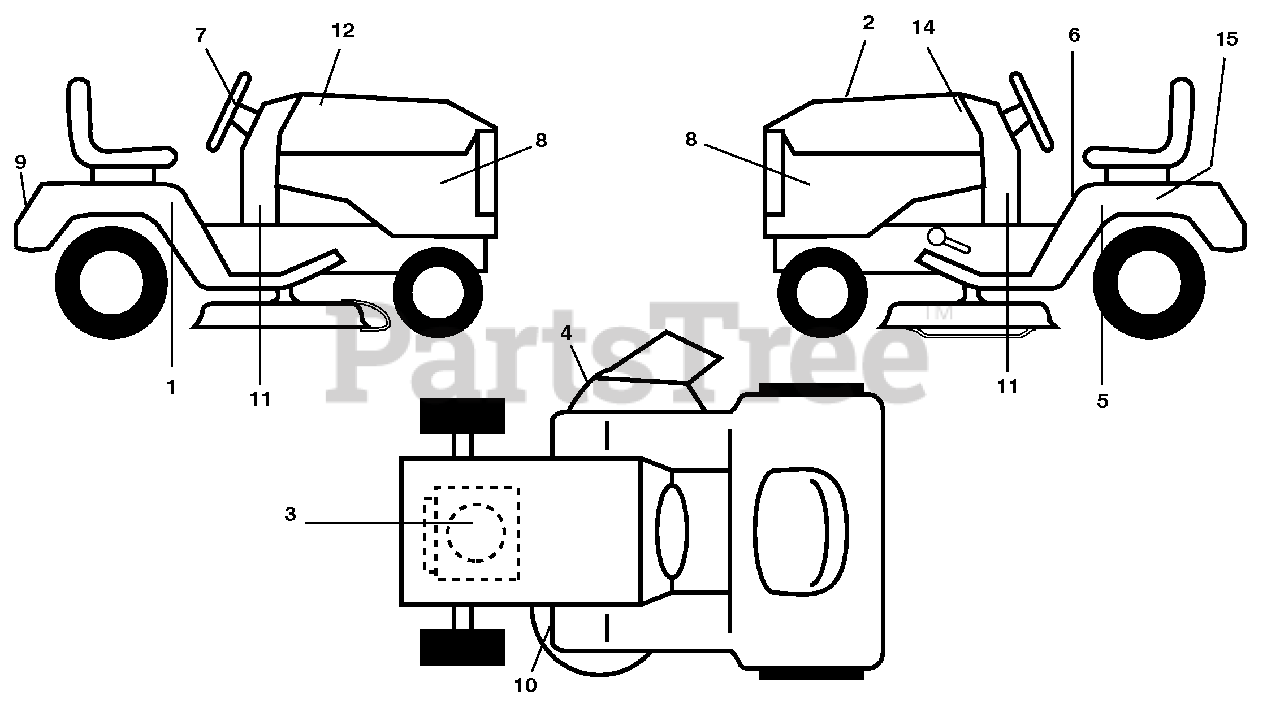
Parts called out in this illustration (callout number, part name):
1	Decal, Fender RH
2	Decal, Replacement
3	Decal, Engine HP
4	Decal, Warning
5	Decal, Fender LH
6	Decal, Fender Danger Eng/Fr
7	Decal, Ins Str Wh
8	Decal, Side Panel
9	Decal, Fender
10	Decal, V-Belt Sch.
11	Decal, Lower Dash
12	Decal, Hood RH
14	Decal, Hood LH
15	Decal, Caution, Battery
15	Decal, Handle Lft Height Adj.
15	Pad Footrest LH
15	Pad Footrest RH
15	Manual, Operator's (E&F)
15	Manual, Parts (E&F)
